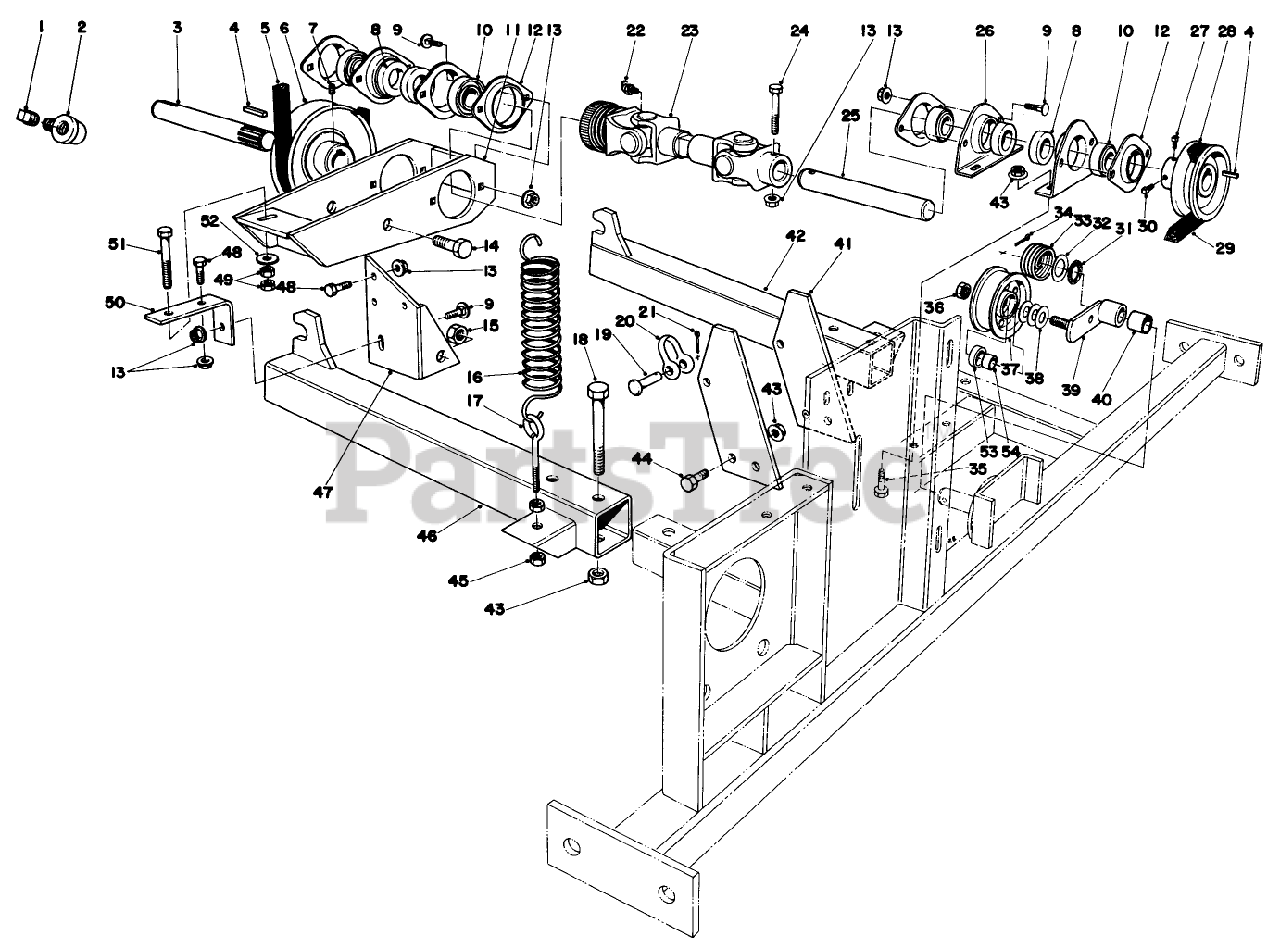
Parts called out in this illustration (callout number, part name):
1	PLUG-PIPE, SQH
2	Elbow
3	Jackshaft
5	V-Belt
6	Pulley
7	SCREW-SET
8	COLLAR-LOCK, BEARING
9	BOLT-CARR
10	Bearing (Incl. Ref. #8)
11	Bearing Support
12	Flange
13	NUT-HF
14	SCREW-HH
15	NUT-HF
16	Extension Spring
17	Eyebolt
18	SCREW-HH
19	PIN-CLEVIS
20	SHACKLE
21	PIN-COTTER
22	Grease Fitting
23	Power Take Off Shaft
24	SCREW-HH
25	JACKSHAFT
26	FLANGE
27	5/16-18 X 1/2 SQ HD
28	SHEAVE 60103
29	V-BELT
30	SCREW-SQH
31	Felt Washer
32	Washer
33	Spring-Torsion
34	PIN-COTTER
35	SCREW-HH
36	LOCKNUT 6239
37	Idler Pulley
38	WASHER-FLAT
39	Idler Arm (Incl. Ref. #40)
40	BUSHING 16162
41	Lifting Lug
42	Tool Bar L.H.
43	NUT-HHF, WHIZ
44	SCREW-HH
45	NUT-HEX
46	Tool Bar R.H.
47	Hinge Plate
48	SCREW-HH
49	NUT-HEX
50	Angle Support
51	Machine Screw
52	WASHER-FLAT
53	Bearing
54	Sleeve
